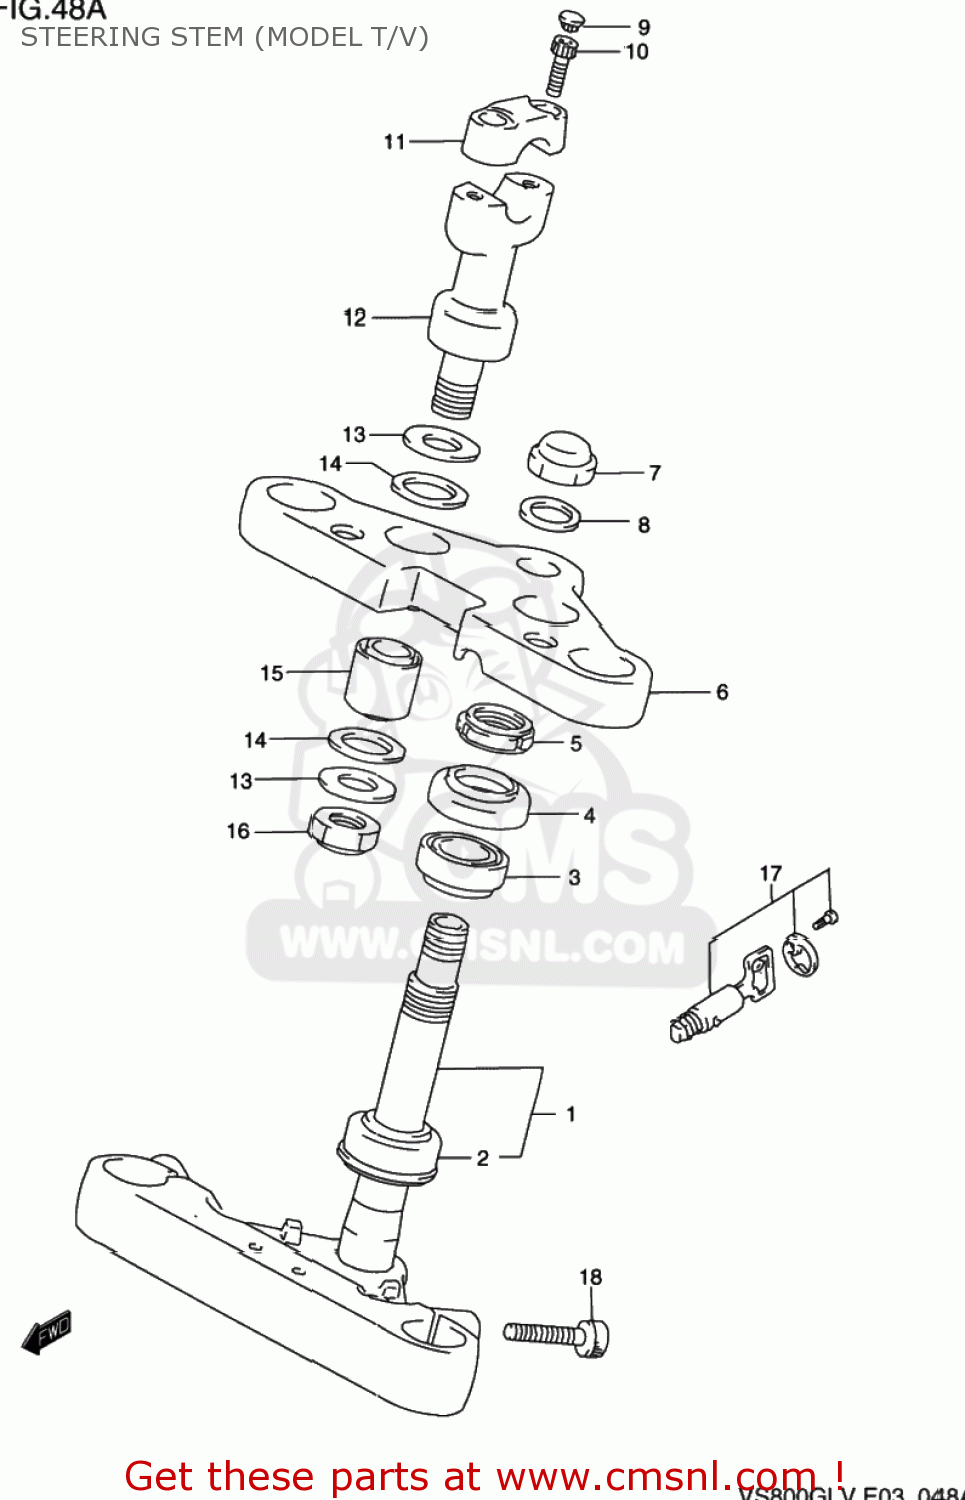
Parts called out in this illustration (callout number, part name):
1	STEM,STEERING
2	BEARING(30X55X17)
3	BEARING(25X47X15)
4	SEAL,STEERING UPR DUST
5	NUT,STEERING STEM(25X44X10)
6	HEAD,STEERING STEM
7	NUT,CAP
8	WASHER(22.5X32X1.6)
9	CAP(OD:14.5)
10	BOLT
11	HOLDER,HANDLE UPR
12	HOLDER,HANDLE
13	WASHER
14	SEAT,RUBBER
15	CUSHION
16	NUT
17	LOCK SET,STEERING
18	BOLT
